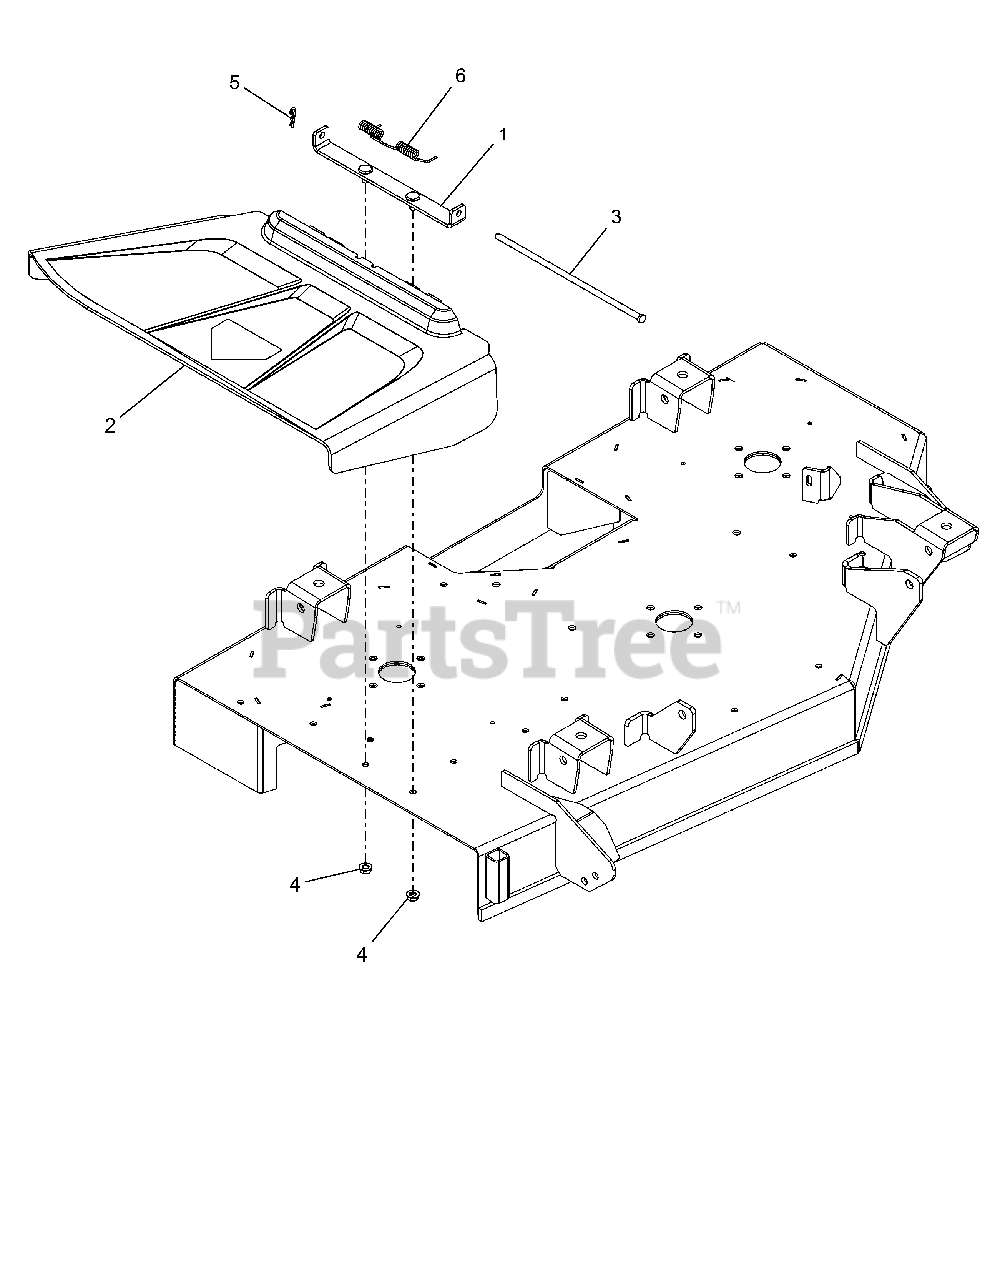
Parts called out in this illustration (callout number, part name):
1	WLDMT, CHUTE MT BRKT
2	CHUTE, SIDE DISCHARGE
3	PIN, 5/16 X 10.5
4	@NUT-LK-TOP-FLG .31-18 YWZC
5	PIN-HAIR INT .08X.18X1.18 YWZC
6	SPRING-TORSION
